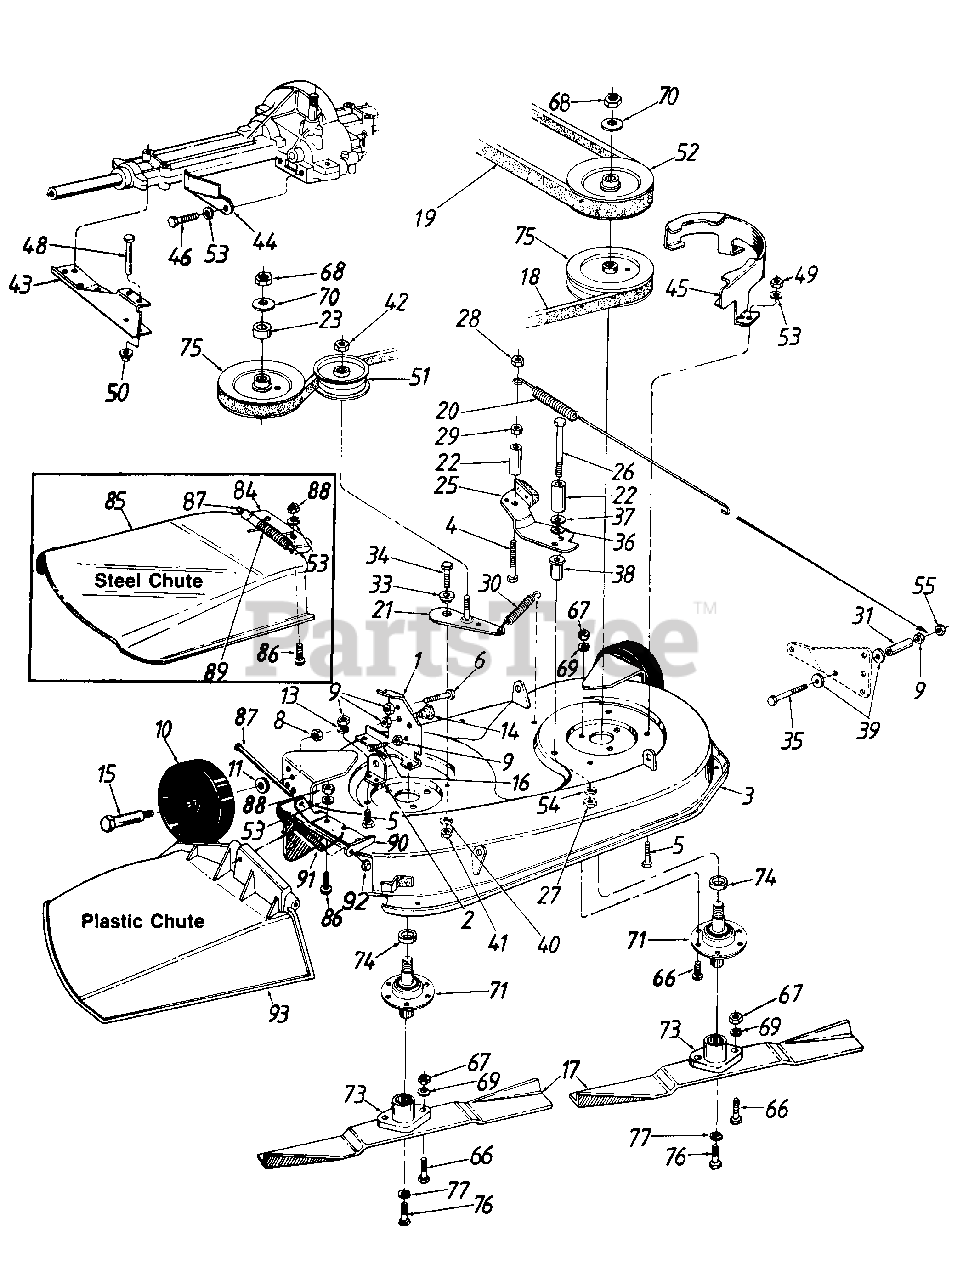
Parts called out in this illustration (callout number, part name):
1	Deck Disengagement Brkt.
2	Rear Deck Brkt.-R.H.
3	32" Deck Ass'y.
4	Hex Bolt 1/4-28 x 1.75" Lg.
5	Hex Bolt 1/4-20 x .62" Lg.
6	Hex Wash. Hd. Scr. 1/4-20 x 1.5" Lg.
8	Hex L-Nut 3/8-16 Thd.
9	Hex Nut 1/4-20 Thd.
10	Deck Wheel
11	Bell-Wash. .380" I.D. x .88"
13	L-Wash. 1/4" I.D.*
14	Shld. Bolt .500" Dia. x .215"
15	Shld. Bolt .498" Dia. x 1.53"
16	Hex Tap Scr. 1/4-20 x .75" Lg.
17	R.H. High-Lift Blade
18	V-Belt
19	V-Belt
20	Extension Spring 15-518" Lg.
21	Idler Brkt. Ass'y.
22	Spacer 5/16" I.D. x 1/2" O.D. x 31132"
23	Spacer .752" I.D. x 1.25" O.D.
25	Deck Brake Brkt. Ass'y.
26	Hex Bolt 5/16-18 x 3.25" Lg.
27	Hex Nut 5/16-24 Thd.
28	Hex L-Nut 1/4-28 Thd.
29	Hex Nut 1/4-28 Thd.
30	Extension Spring 4.35" Lg.
31	Spacer 1/4" I.D. x 318" O.D. x 1-5/16"
33	Shoulder Spacer
34	Hex Bolt 3/8-16 x 1" Lg.
35	Hex Bolt 1/4-20 x 2.5" Lg.
36	Wave Washer
37	Shld. Spacer .27" Lg.
38	Spacer 1.46" Lg.
39	Flat Wash. 1/4"
40	L-Wash. 3/8" I.D.
41	Hex Nut 3/8-16 Thd.
42	Hex L-Nut 3/8-24 Thd.
45	Belt Guard Deck-R.H.
46	Hex Bolt 1/4-20 x .62" Lg.
49	Hex Nut 1/4-20 Thd.*
50	Speed Nui 1/4" Rod
51	Flat Idler Pulley
52	5" Dia. Pulley
53	L-Wash. 1/4" I.D.
54	Bell-Wash. 5/16" I.D.
55	Hex L-Nut 1/4-20 Thd.
66	Hex Bolt 5/16-24 x 1 " Lg.
67	Hex Nut 5/16-24 Thd.
68	Hex Jam Nut 5/8-18 Thd.
69	L-Wash. 5/16" I.D.
70	Bell-Wash. 5/8" I.D.
71	Blade Spindle Ass'y. Comp.
73	Blade Adapter
75	5" Dia. Pulley
76	Hex Bolt 3/8-24 x 1.0" Lg.
77	L-Wash. 3/8" I.D. H.D.
84	Chute Bracket (Steel)
85	Chute (Steel)
86	Truss.-Mach. Scr. 1/4-20 x .75" Lg.
87	Hinge Pin
88	Hex Nut 1/4-20 Thd.
89	Torsion Spring 1.14" Lg.
90	Hinge Mtg. Brkt.
91	Torsion Spring
93	Chute Ass'y. Comp. (Plastic)
